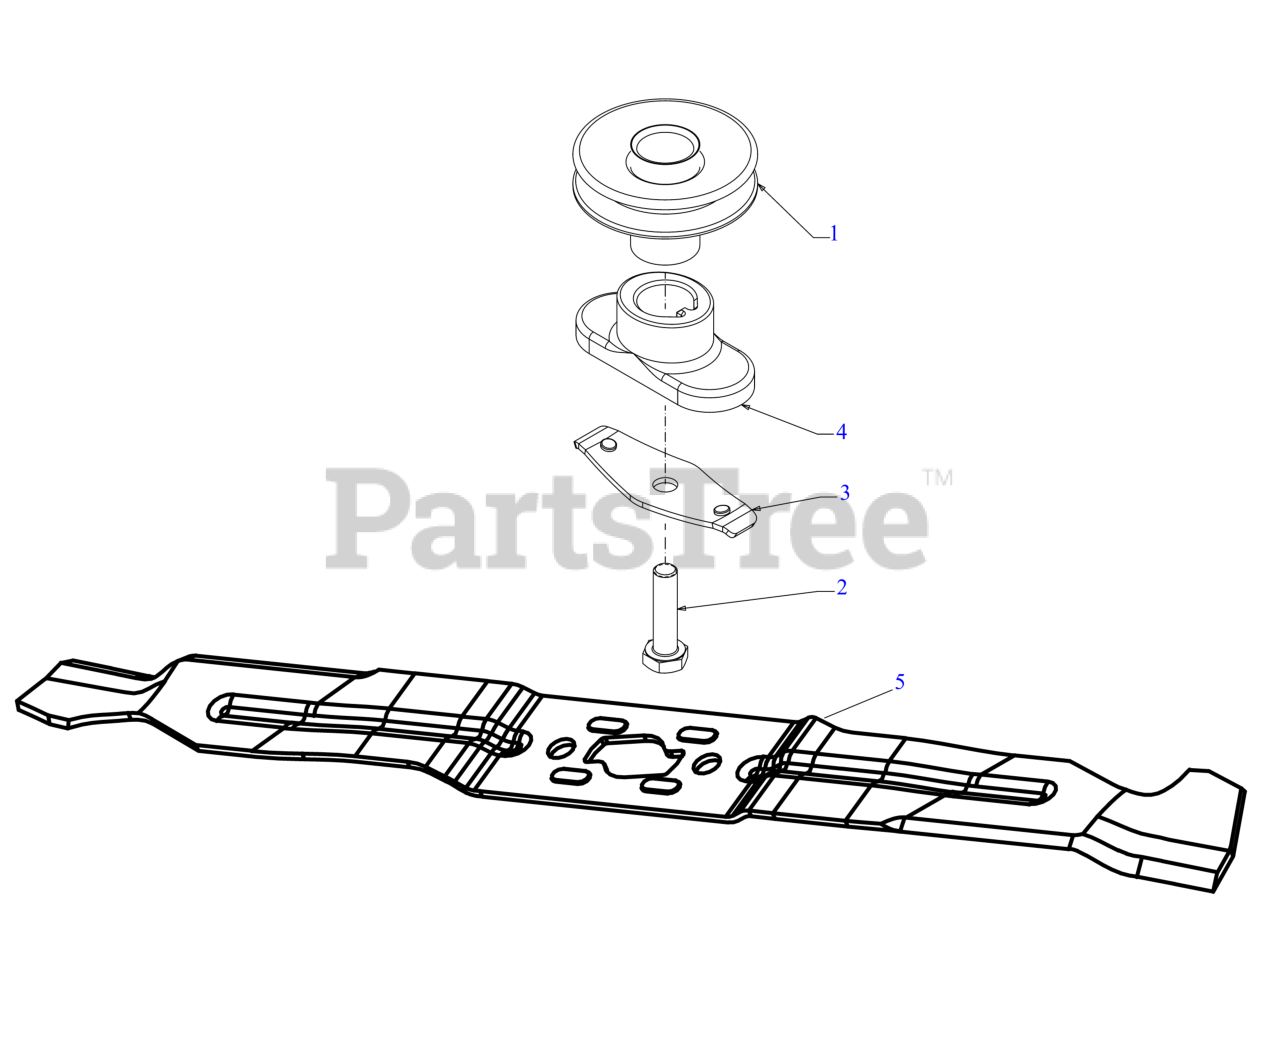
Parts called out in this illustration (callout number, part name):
1	ADAPTER (7/8" VARI 2.66 )
2	SCREW 3/8-24 x 1.50 GR8
3	BLADE BELL SUPPORT
4	BLADE ADAPTER (#6 X 1.19 W/S)
5	21" MULCH BLADE (S SHAPE CENTER HOLE)
